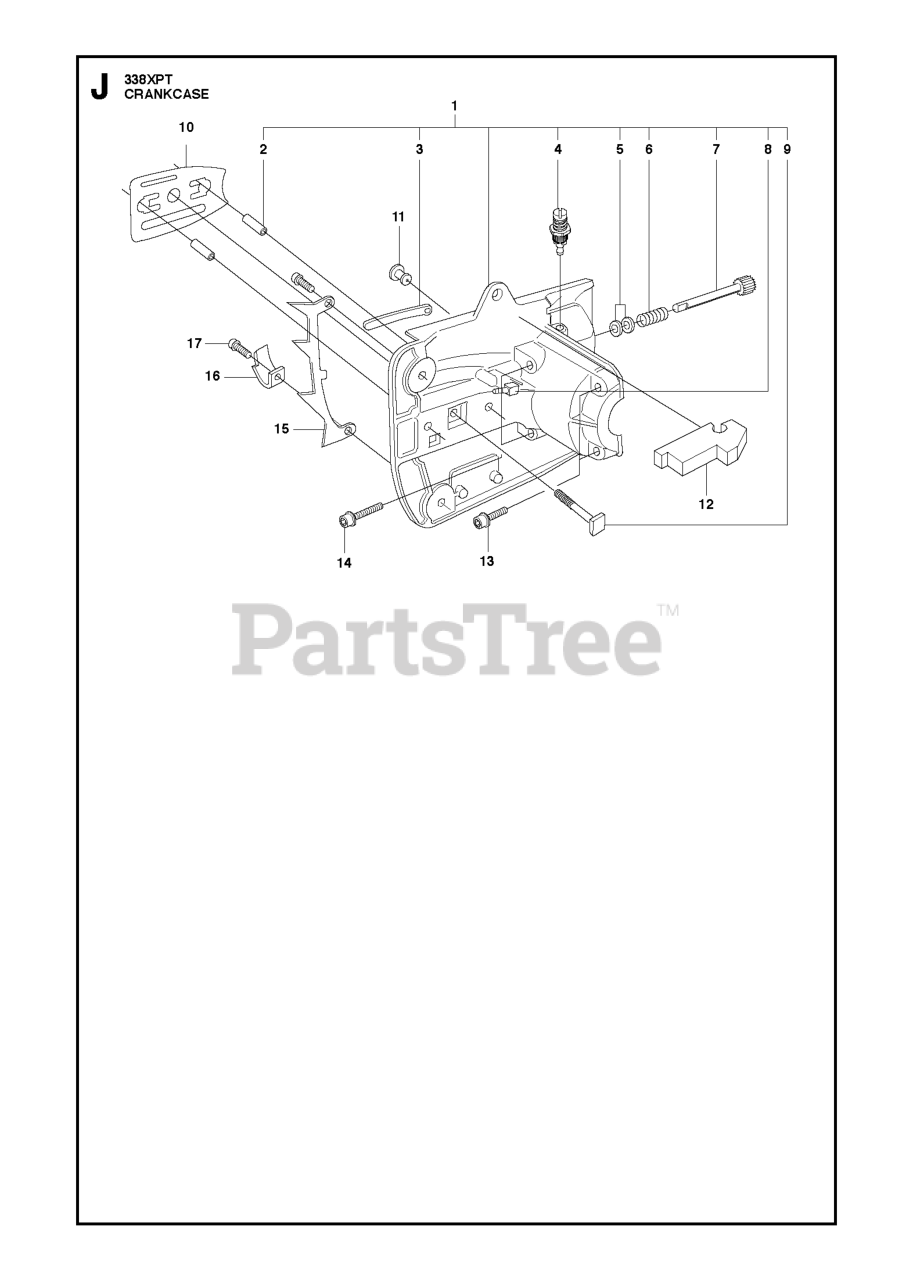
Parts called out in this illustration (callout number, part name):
2	GUIDE BAR LOCATING PIN
4	INSERT OIL PUMP
5	WASHER 5.1X8.5
7	PUMP PISTON
10	CHAIN GUIDE PLATE
12	FOAM INSULATOR
15	FELLING DOG
16	CHAIN CATCHER
